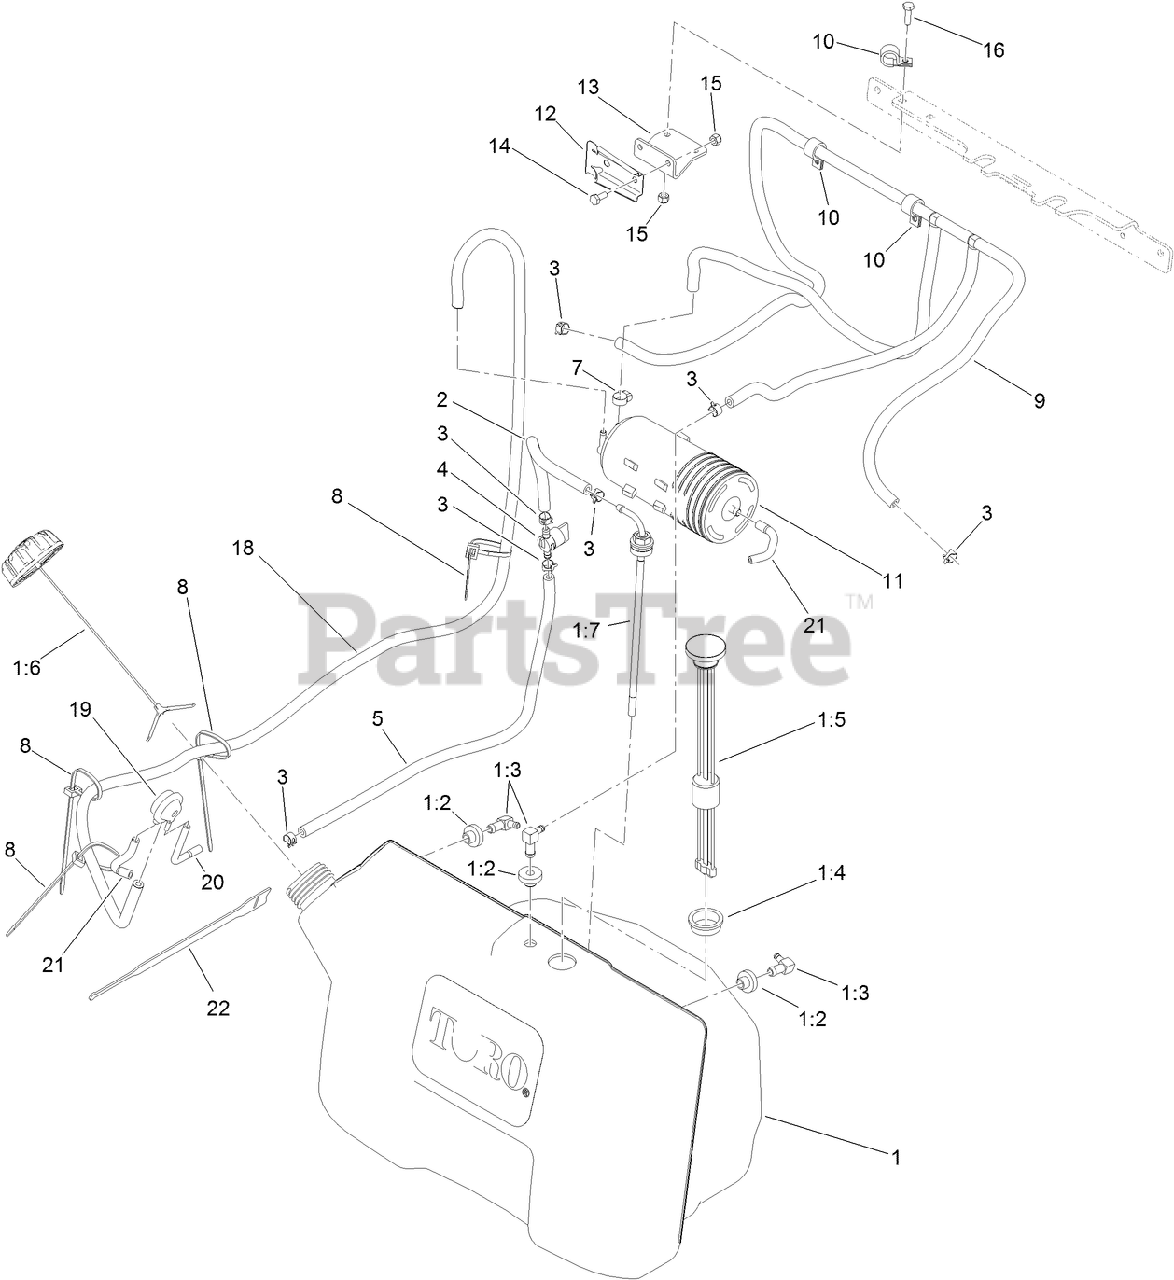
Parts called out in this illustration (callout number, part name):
1	TANK ASM
1:2	BUSHING
1:3	ELBOW-90 DEG
1:4	GROMMET
1:5	GUAGE-FUEL
1:6	CAP-FUEL, RATCHETING
1:7	FITTING-FUEL, BULKHEAD
2	HOSE-FUEL
3	CLAMP-HOSE
4	VALVE-FUEL
5	HOSE-FUEL
7	CLAMP-WORM
8	TIE-CABLE
9	VENT HOSE ASM
10	CLAMP-CABLE
11	CANISTER-CARBON, 800CC
12	BRACKET-CANISTER, CARBON
13	BRACKET-CANISTER
14	SCREW-HH
15	NUT-HF
16	SCREW-HH
18	HOSE-FUEL
19	VALVE-CONTROL, VACUUM
20	HOSE-VENT, FORMED
21	HOSE-VENT, FORMED
22	STRAP-VELCRO, CABLE TIE
